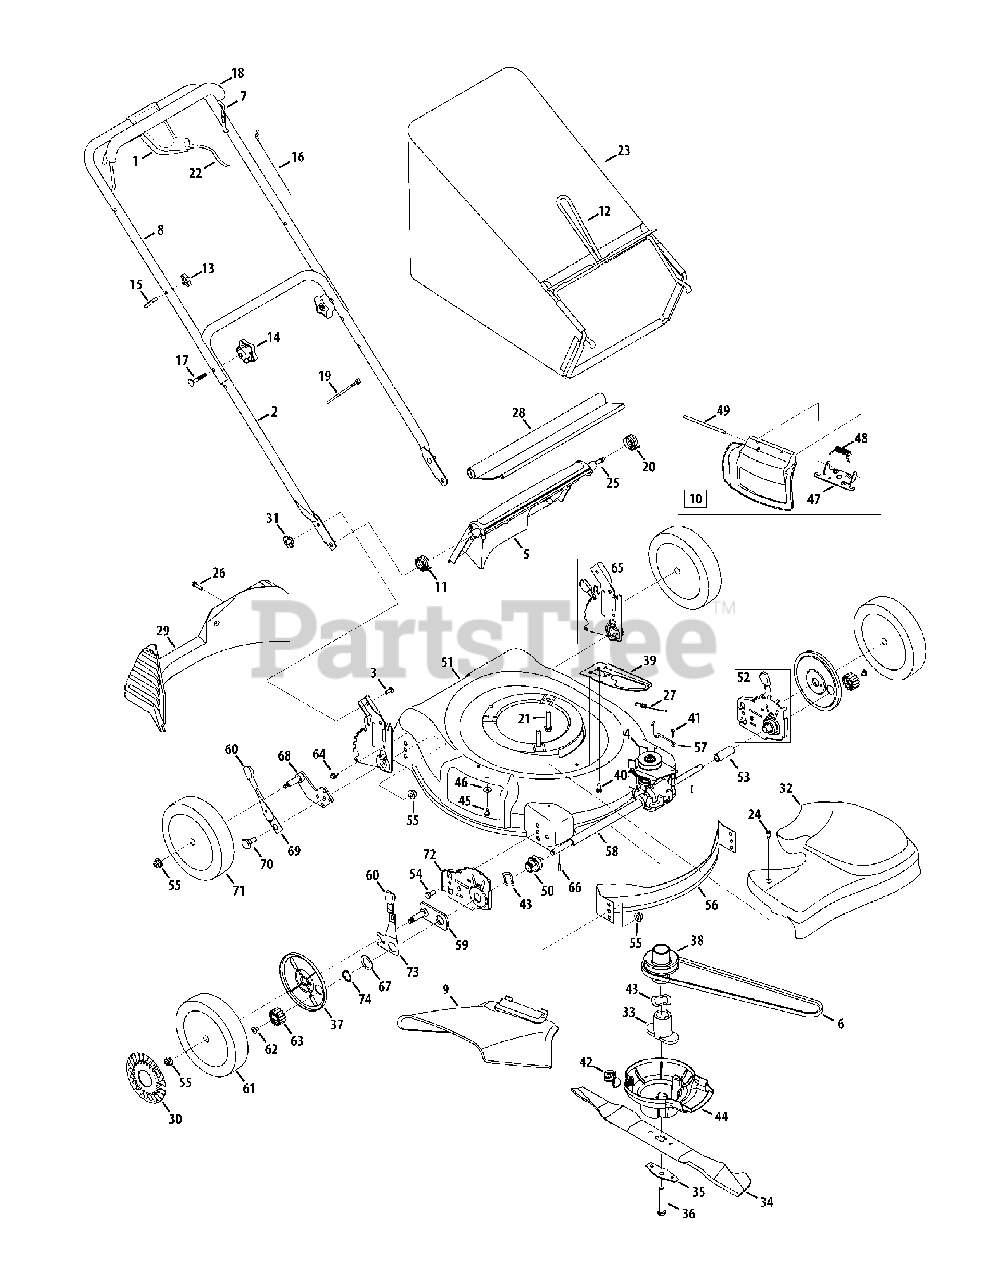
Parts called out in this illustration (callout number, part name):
1	Drive Control Assembly
3	Carriage Bolt 1/4-20
4	Transmission Assembly
5	Rear Discharge Door
6	V-Belt
10	Mulch Plug Complete
11	Torsion Spring - RH
13	Handle Knob
14	Handle Knob
16	Control Cable
17	Carriage Bolt 5/16-18 x 2.0
18	Bail Cover
19	Cable Tie
20	Torsion Spring - LH
21	Self-Tapping Sems Screw
22	Drive Cable
23	Grassbag
24	Shoulder Screw # 12 -24
26	Screw, 1/4-15 x 1.00
27	Extension Spring
28	Rear Trailing Shield
29	Rear Baffle
30	Hub Cap
31	Wing Nut
32	Transmission Cover
33	Blade Adapter
34	21" Mulching Blade
35	Blade Bell Support
36	Hex Screw 3/8-24 x 2.50
37	Wheel Dust Cap
38	Drive Pulley Assembly
40	Screw, 1/4-14 x .625
41	Screw, .159 OD x .610
42	Engine Baffle Bracket
43	Washer, Wave, 1.5 x 1.0 x .029
44	Engine Baffle
45	TT Screw 1/4-20 x 0.5
46	Bell Washer.265 x 0.75
47	Deflector Chute Adapter
48	Torsion Spring
49	Hinge Pin
50	Bearing Assembly
52	Height Adjustment Ass’y - LH
53	Sleeve Spacer, 1.8" Lg.
54	Hex Screw, 3/8-16 x.75
55	Flange Lock Nut, 3/8-16
56	Front Baffle
57	Belt Keeper Wire
58	Sleeve Spacer, 9.10" Lg.
59	Pivot Plate Assembly
60	Adjustment Knob
61	Front Wheel, 8 x 2.125
62	Screw, 1/4-20 x .390
63	Gear 14T RH FWD
63	Gear 14T LH FWD
64	TT Scr. w/Washer 1/4-20 x.625
65	Handle Bracket Assembly - RH
65	Handle Bracket Assembly - LH
66	Dowel Pin
68	Pivot Arm Assembly - RH
68	Pivot Arm Assembly - LH
69	Rear Spring Lever
70	Shoulder Scr., 500 Dia. x. 385
71	Rear Wheel, 8 x 2.125
72	Height Adjuster Plate - RH
72	Height Adjuster Plate - LH
73	Front Lever - RH
73	Front Lever - LH
74	Snap Ring
